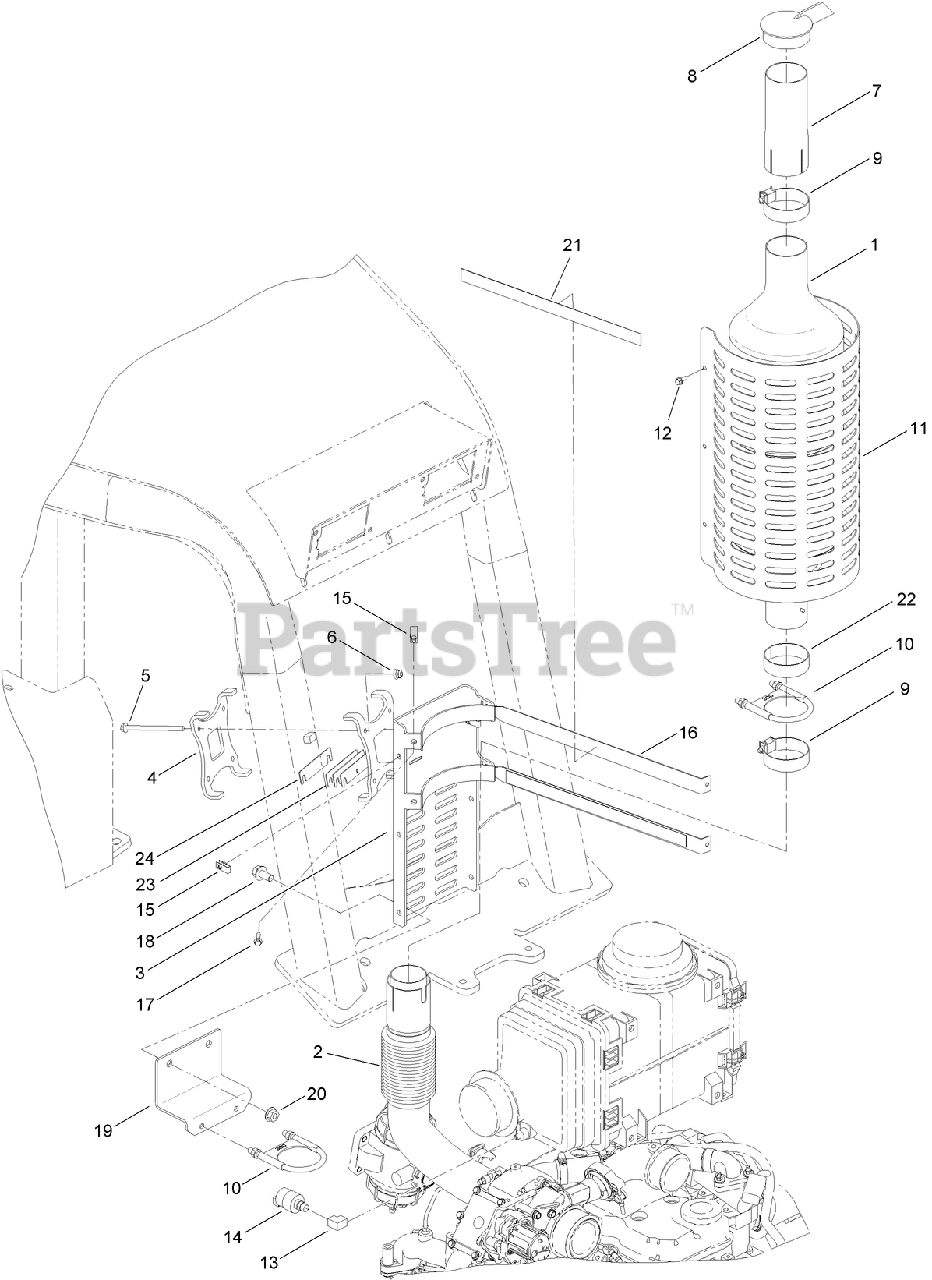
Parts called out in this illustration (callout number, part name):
1	MUFFLER
2	TURBO PIPE ASM
3	MOUNT-MUFFLER
4	PLATE-BENT
5	SCREW-FLANGE, METRIC
6	NUT-LOCK, HHF
7	TUBE-EXHAUST
8	CAP-RAIN
9	CLAMP-TORCTITE
10	CLAMP-GUILLOTINE
11	SHIELD-MUFFLER
12	SCREW-HHF
13	FITTING-ELBOW, 90
14	SWITCH ASM
16	STRAP-MUFFLER
17	SCREW-HHF
18	SCREW-HHF
19	PLATE-RETAINER
20	NUT-HHF
21	TAPE-ADHESIVE, MUFFLER
22	TAPE-ADHESIVE, INLET
23	PLATE-SHIM
24	PLATE-SHIM
